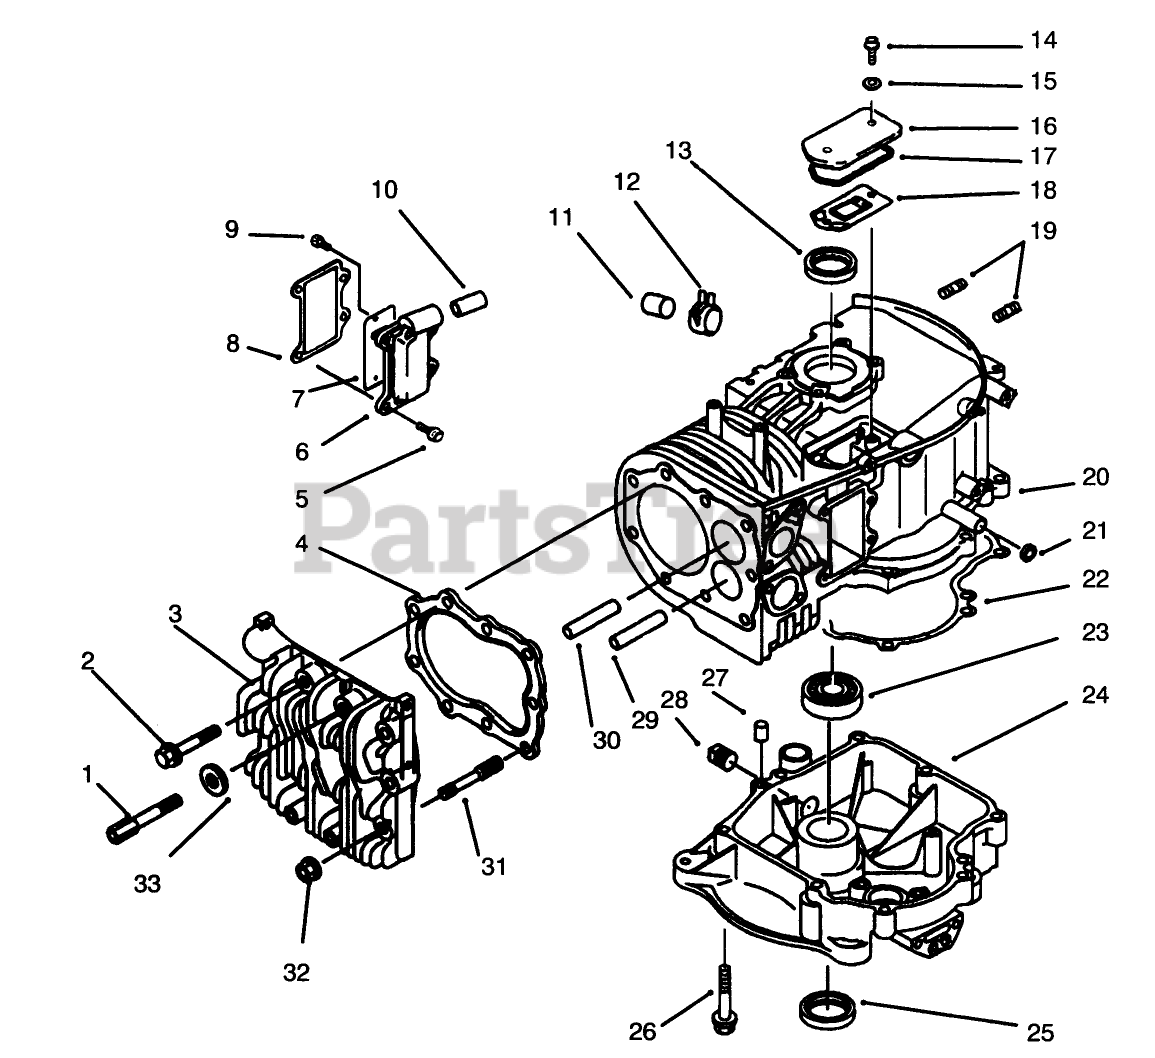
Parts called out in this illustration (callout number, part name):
1	Bolt
2	Bolt
3	Head-Cylinder
4	Gasket-Head
5	Bolt-Flanged (6X16)
6	Cover-Valve Chamber
7	Cover
8	Gasket
9	Screw
10	Tube
11	Plug
12	Clamp
13	Oil Seal
14	Bolt
15	Gasket
16	Cover
17	Gasket
18	Breather
19	Stud
20	Crankcase-Complete (Incl. Ref. #29, 30)
21	SEAL-OIL (VC6X10X2.6)
22	Gasket-Crankcase
23	Ball Bearing
24	Cover-Crankcase
25	Oil Seal
26	Bolt-Flanged (8X45)
27	Pin
28	Plug
29	Guide-Exhaust Valve
30	Guide-Intake Valve
31	Stud
32	Nut
33	Washer
